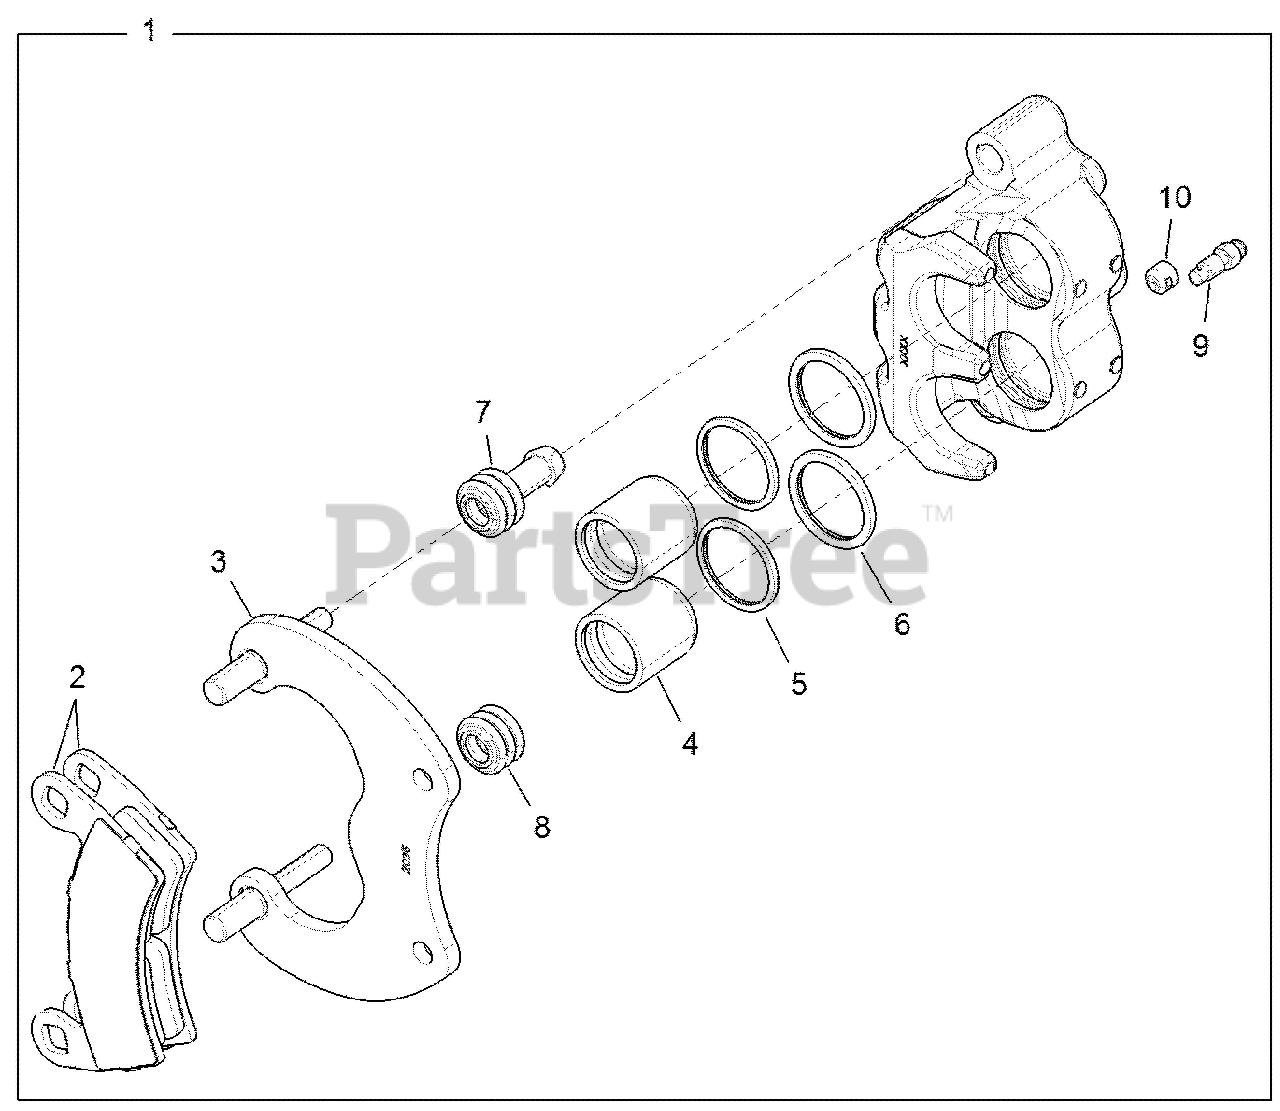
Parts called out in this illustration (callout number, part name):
1	ASM.,BRAKE,CALIPER,LH,GROOVED
1	ASM.,BRAKE,CALIPER,RH,GROOVED
2	KIT-ASM,PAD,BRAKE,DB,1.375
3	ASM., CALIPER, MOUNT
4	PISTON-BRAKE,1.188",AL,GROOVED
5	RING,SQUARE,MOLDED,.094
6	RING,SQUARE,MOLDED,.103X.134
7	BOOT-PIN BUSHING
8	BOOT-PIN SEAL
9	SCR-M7X1.0,BLEEDER,OLIVE D
10	SCR-M10X1.0X8,SOC SET-OD
